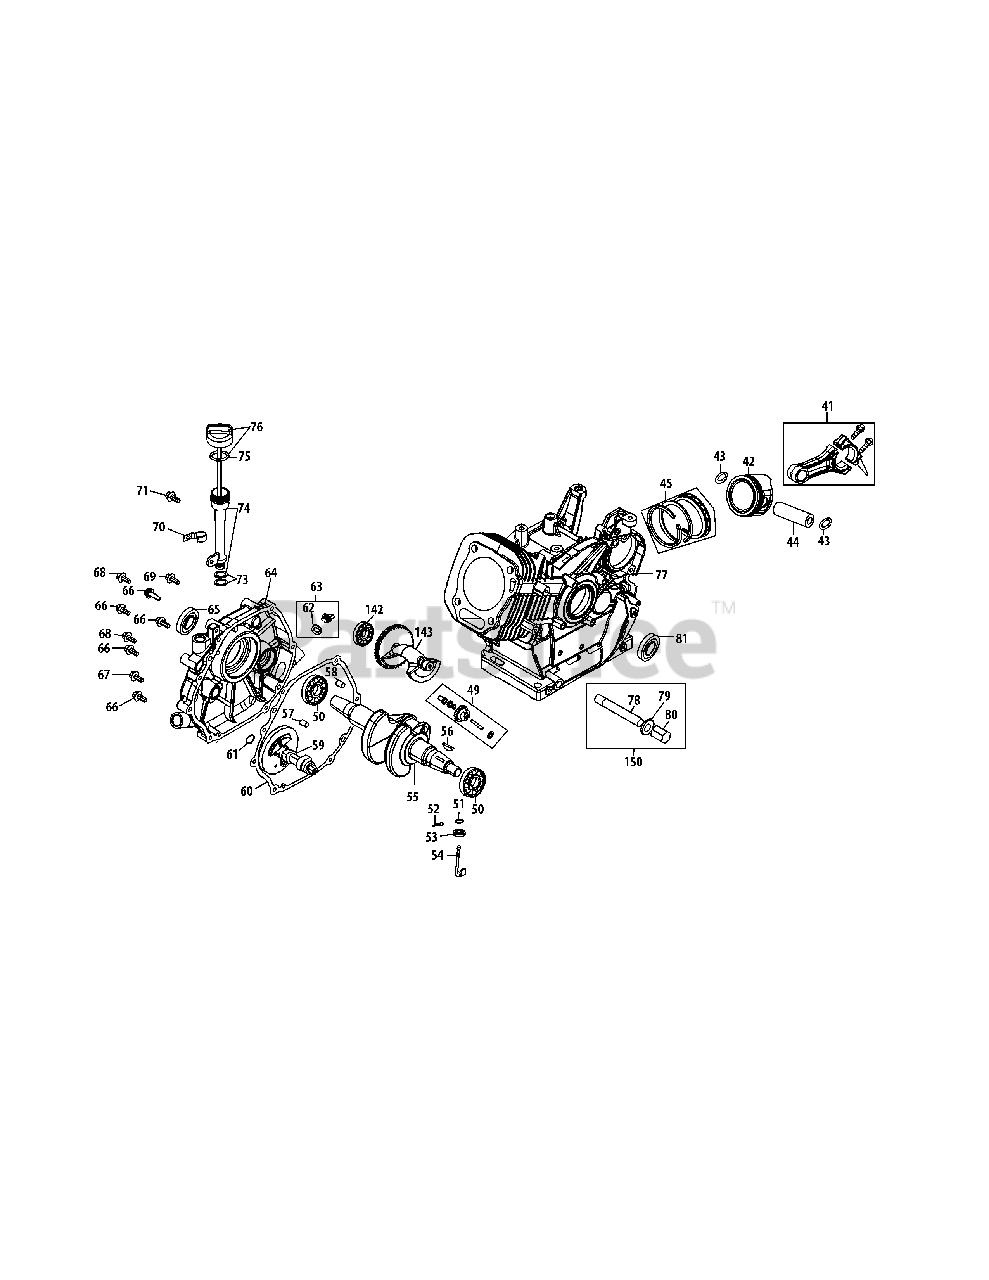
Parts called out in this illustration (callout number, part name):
41	Connecting Rod Ass’y
43	Piston Pin Snap Ring
44	Piston Pin
45	Piston Ring Set
49	Governor Gear/Shaft Ass’y
50	Radial Ball Bearing
52	Cotter Pin
53	Governor Seal
54	Governor Arm Shaft
55	Crankshaft Kit
56	Woodruff Key
57	Dowel Pin, 9 x 12
58	Dowel Pin, 7 x 14
59	Camshaft Ass’y
60	Crankcase Cover Gasket
63	Oil Filler Plug Ass’y
64	Crankcase Cover Kit
65	Oil Seal
66	Bolt, M8 x 38
67	Bolt, M8 x 45
68	Bolt, M8 x 35
70	Dipstick Clamp
71	Bolt, M6 x 8
73	Fill Tube O-Ring
73	Oil Fill Tube O-Ring
74	Oil Fill Tube Assembly
75	Dipstick O-Ring
76	Dipstick Ass'y
77	Crankcase Kit
78	Oil Drain Pipe Ass’y
79	Oil Drain Washer
80	Drain Plug
81	Oil Seal
150	Oil Drain Ass’y
